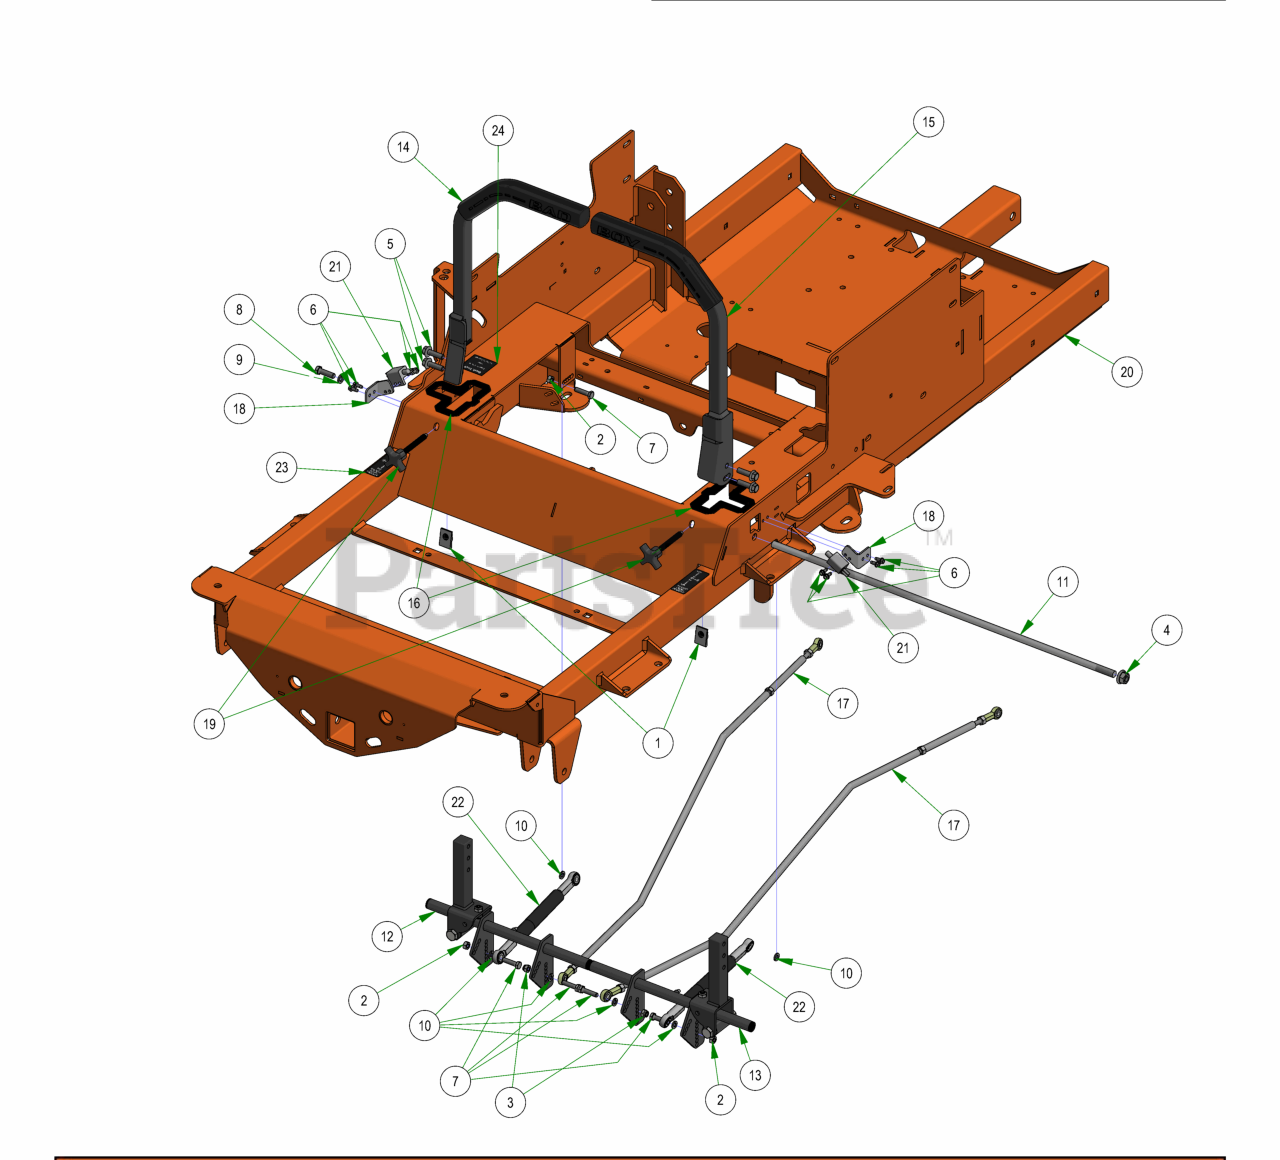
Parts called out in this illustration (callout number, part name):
1	Extruded Nut 3/8"-16 3/4" Hole Center With Patch
2	5/16-18 HEX NUT ZINC
3	5/16-18 NYL INS L/N ZC
4	1/2-13 NYLON INSERT FLANGE LOCKNUT ZINC
5	3/8-16 X 1 1/4 HEX WASHER UNSLOT MACHINE SCREW ZINC GR5
6	12-24 X 1/2 HEX WASHER UNLSOT F TCS ZINC
7	5/16-18 X 1-1/4 HEX C/S (GR.5) ZC
8	3/8-16 X 1-1/4 HEX CAP SCREW (GR.5) ZINC
9	3/8 SPLIT LOCKWASHER ZINC
10	5/16 SPLIT LOCKWASHER ZINC
11	2019 Steering Actuator Rod
12	R Series Square Drive Arm Actuator RH Assembly
13	R Series Square Drive Arm Actuator LH Assembly
14	R Series Square Drive Arm RH Assembly
15	R Series Square Drive Arm LH Assembly
16	Snap-in Drive Arm Bushing
17	2019 Renegade Push Rod Assembly
18	2019 Arm Switch Bracket
19	Speed Limiting Knob 3/8-16X 3"
20	2019 Renegade Gas Frame - Powdercoated
21	Safety Switch
22	2019 SROID Damper With Spherical Rod Ends
23	2018 LH/RH Steering Control Decal Roll
24	2019 Deck Release Decal
